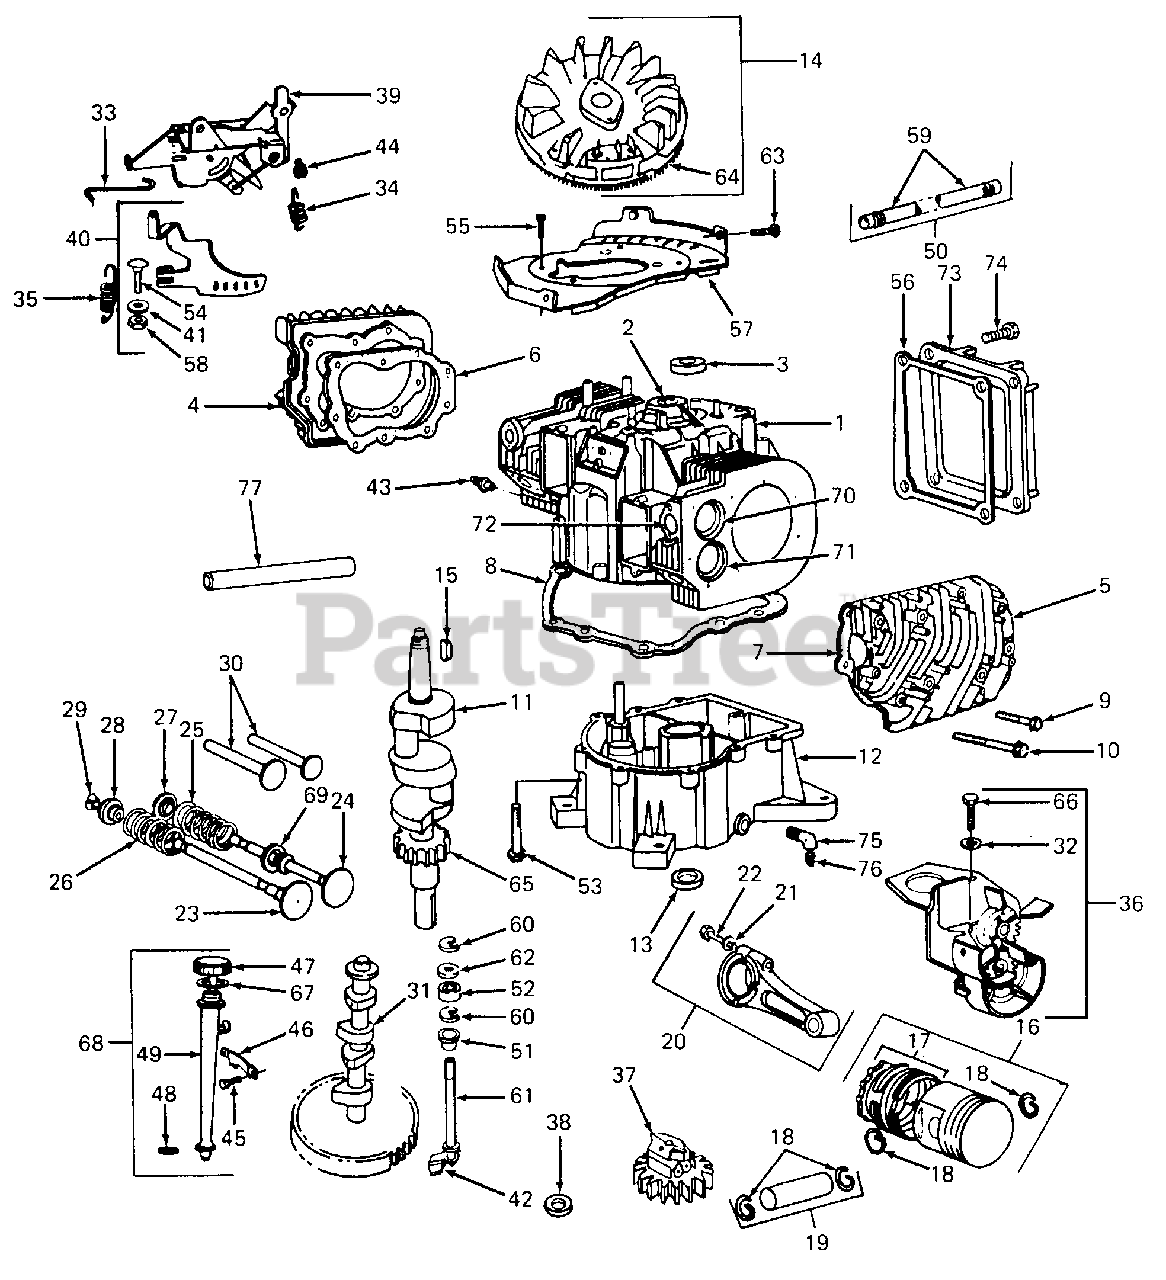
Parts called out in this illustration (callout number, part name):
1	Cylinder Assembly
2	Bearing, Cylinder
3	Seal, Oil
4	Head, Cylinder #1
5	Head, Cylinder #2
6	Gasket, Cylinder Head #1
7	Gasket, Cylinder Head #2
8	Gasket, Crankcase Cover 1/64 in. thick
9	Screw, Cylinder Head, 1-15/16 Lg
10	Screw, Cylinder Head, 2-5/16 Lg
11	Crankshaft
12	Base Assembly, Crankcase
13	Seal, Oil
14	Flywheel & Ring Gear Assy, Magneto
15	Key, Flywheel
16	Piston Assy, Standard
17	Ring Set, Piston, Standard
18	Lock, Piston Pin
19	Pin Assy, Piston, Standard
20	Rod Assy, Connecting
21	Washer, 1/4 X 5/8 X 1/32
22	Screw, Connecting Rod
23	Valve, Exhaust
24	Valve, Intake
25	Spring, Intake Valve
26	Spring, Exhaust Valve
27	Retainer, Intake Valve
28	Rotocoil, Exhaust Valve
29	Retainer, Exhaust Valve Rotocoil
30	Tappet, Valve
32	Washer, Lock No. 10 X 1/16 X 3/64
33	Link, Governor
34	Spring, Governor
35	Spring, Governor Idle
36	Oil Slinger Assy
37	Gear, Governor
38	Washer, Thrust
39	Plate Assy, Governor Control
40	Lever Assy, Governor
42	Washer, Governor Crank
43	Connector, Impulse Pump
44	Screw, Sem
45	Screw, Hex Hd
46	Clamp, Oil Filler
47	Cap & Dipstick, Oil Filler
48	Seal, Filler Tube
49	Tube, Oil Filler
50	Impulse Line & Clamp Assy
51	Lower Bushing, Governor
52	Upper Bushing, Governor
53	Screw, Hex Hd Sem
54	Bolt, Governor Lever
55	Screw, Hex Head
56	Gasket, Crankcase
57	Back Plate Assy
58	Nut, Hex 10-24
59	Clamp, Fuel Line
60	Retainer, E-Ring
61	Crank, Governor
62	Foam Seal, Governor
63	Screw, Sem
64	Gear, Flywheel Ring
65	Gear, Timing w/ Key
66	Screw, Hex Hd 10-32 X 5/8
67	Seal, Oil Filler Cap
68	Dipstick & Tube Assembly
69	Seal Assembly & Retainer
70	Seat, Intake Valve, Standard
71	Seat, Exhaust Valve, Standard
72	Guide, Exhaust Valve (Only)
73	Cover Plate, Crankcase
74	Screw, Crankcase Cover Mtg. Sem
75	Tube, Oil Drain
76	Plug, 1/4-18 ZNP H/Hd Auto Pipe Oil Drain
77	Tubing, Fuel Line Cover
